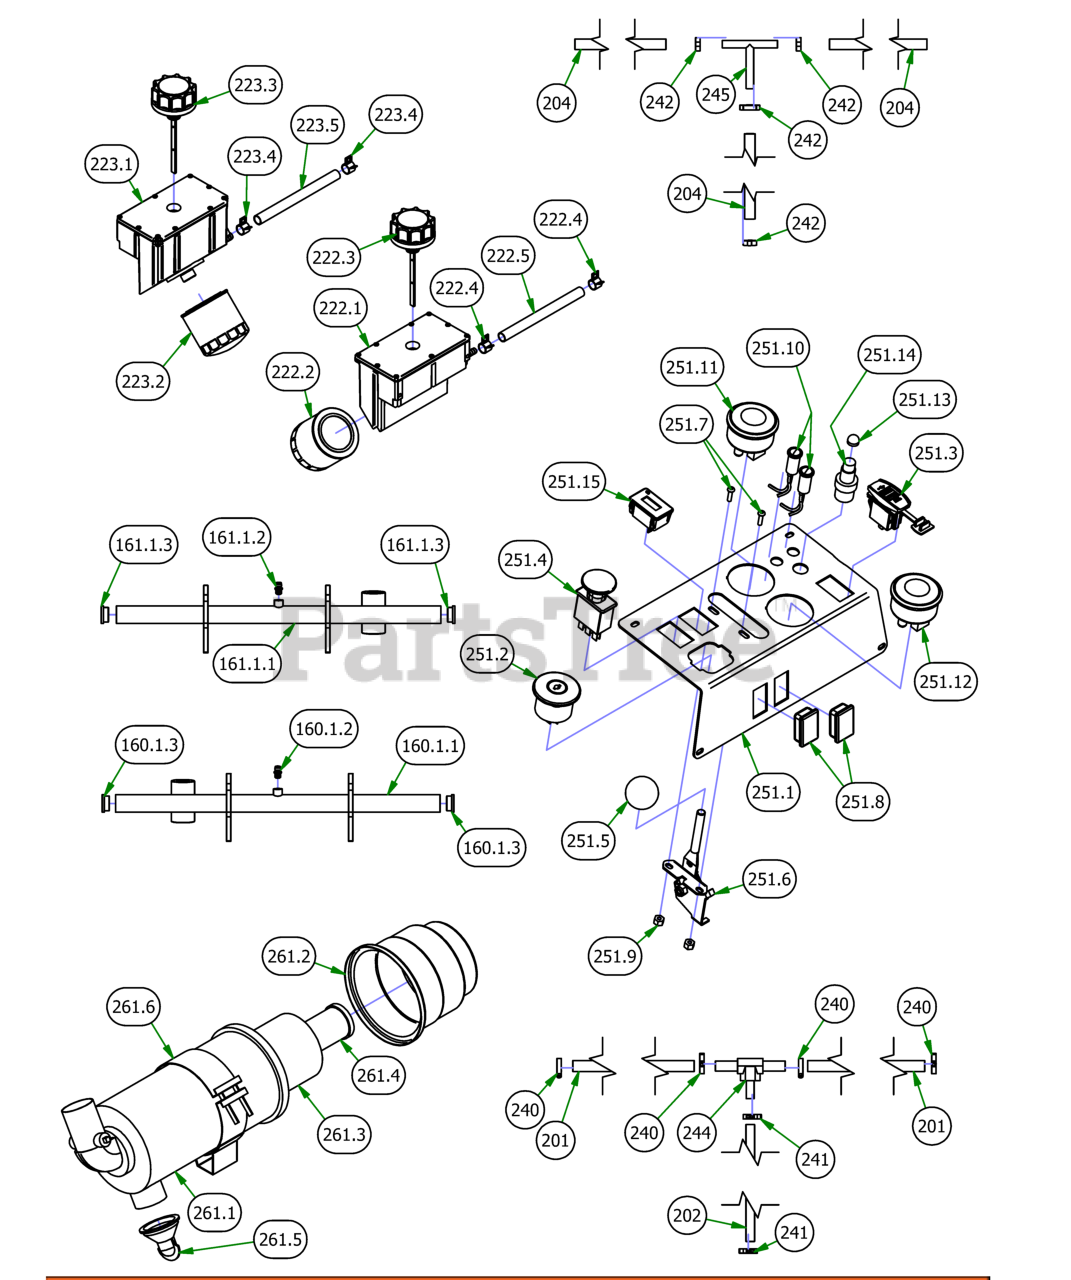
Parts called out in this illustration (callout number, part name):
160.1	2019 Drive Arm Actuator right
160.1.1	2019 Drive Arm Actuator right - Weldment
160.1.2	1/4" Press in Grease Fitting
160.1.3	2019 Drive Arm Bushing
161.1	2019 Drive Arm Actuator left
161.1.1	2019 Drive Arm Actuator left - Weldment
161.1.2	1/4" Press in Grease Fitting
161.1.3	2019 Drive Arm Bushing
201	1/4 Fuel Line Hose - Priced Per Foot
202	3/16 Fuel Line x 36"
204	5/16 Fuel Line Hose - Priced Per Foot
222	LH Rogue Hydro Tank Assy
222.1	2019 Left Outlaw Gen2 Hydro Tank Suspension Only
222.2	Hydraulic Filter
222.3	Hydraulic Tank Cap W/Dipstick
222.4	1/2 Hose Clamp
222.5	1/2 Clear Braded Hose Priced/Foot
223	RH Rogue Hydro Tank Assy
223.1	2019 Right Outlaw Gen2 Hydro Tank Suspension Only
223.2	Hydraulic Filter
223.3	Hydraulic Tank Cap W/Dipstick
223.4	1/2 Hose Clamp
223.5	1/2 Clear Braded Hose Priced/Foot
240	1/4 Fuel Hose Clamp
241	3/16 Vinyl Clamp
242	2 EAR CLAMP 12.5mm-15mm
244	Brass fuel line T
245	5/16 x 5/16 x 1/4 Fuel Line T
251	Renegade Control Panel Assembly
251.1	2019 Diesel Control Panel
251.2	Ignition Switch
251.4	PTO Switch
251.5	Throttle Knob
251.6	Universal Throttle Head
251.7	10-24 X 5/8 BS Button Head Bolt
251.8	Light Plug
251.9	10-24 Nylon Insert Locknut
251.11	2" Oil Pressure Gauge
251.12	2" Water Temperature Gauge
251.13	Start Switch Boot - Diesel
251.14	Momentary Start Switch
251.15	Hour Meter
261	Enginaire Canister VLR-Complet
261.1	Canister for All Diesel Models
261.2	Enginaire Air canister cap
261.3	Diesel Air Filter- Outer
261.4	Diesel Air Filter- Inner
261.5	Debris Plug-Enginaire Filter
261.6	Mounting Bracket For Diesel Air Filter
